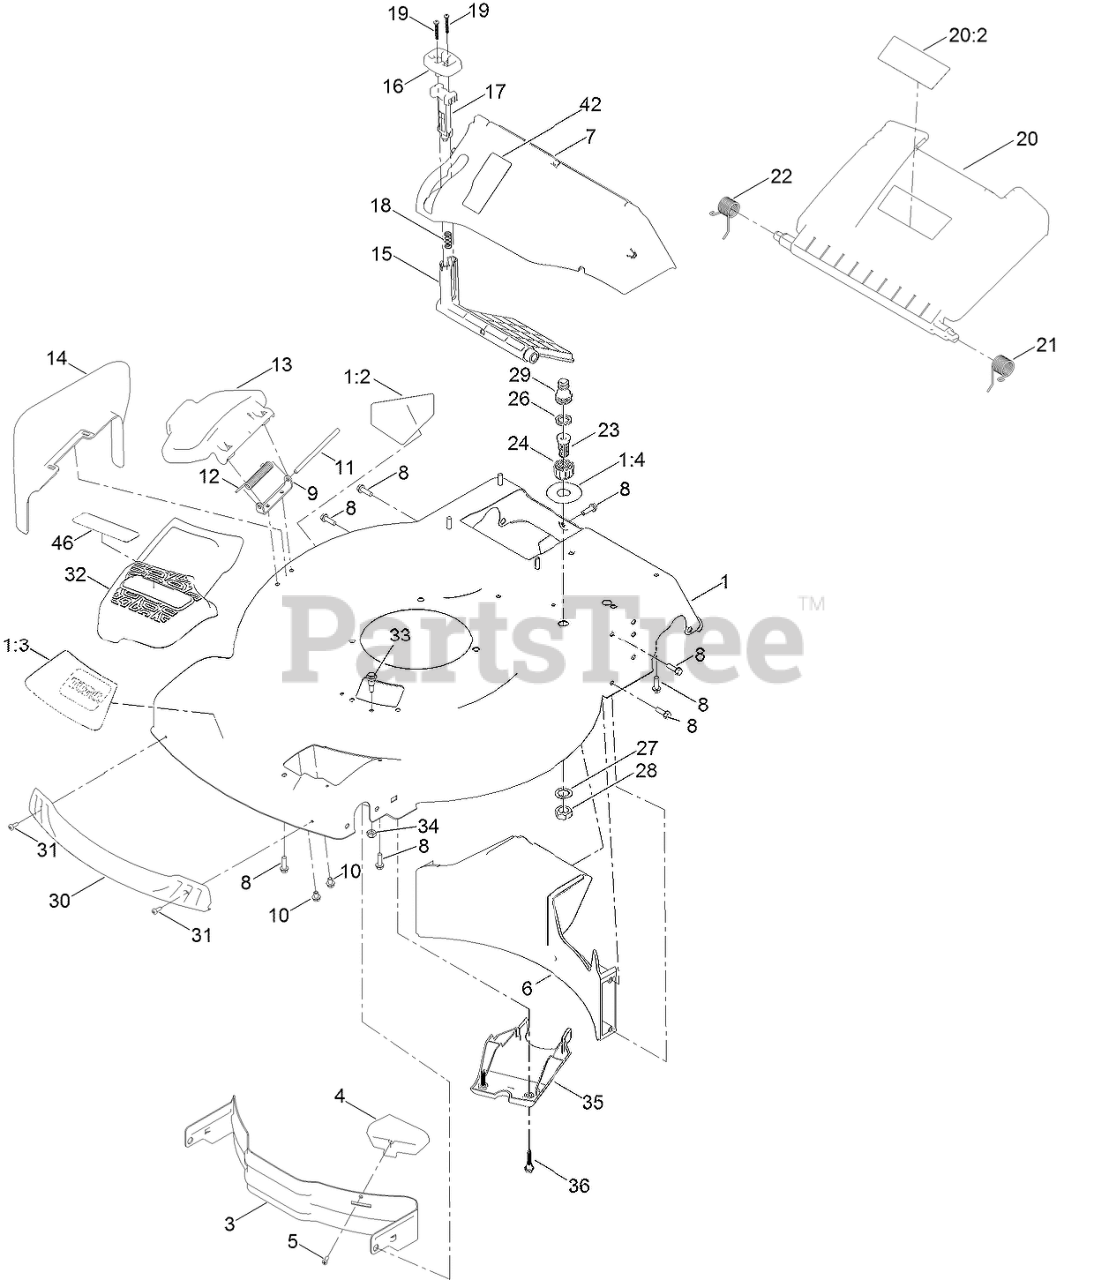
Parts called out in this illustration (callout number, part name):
1	HOUSING ASM
1:2	DECAL-DANGER
1:3	DECAL-DECK
1:4	DECAL-QUICK WASH
3	BAFFLE-FRONT
4	KICKER-FRONT
5	SCREW-PPH
6	BAFFLE-REAR
7	CHUTE-RECYCLE
8	SCREW-HWH
9	BRACKET-COVER
10	SCREW-HWH
11	ROD-COVER
12	SPRING-TORSION
13	DEFLECTOR-SIDE
14	CHUTE-DISCHARGE, SIDE
15	DEFLECTOR-RECYCLE
16	KNOB-RECYCLE
17	LATCH-RECYCLE
18	SPRING-COMPRESSION
19	SCREW-PPH
20	REAR DOOR ASM
20:2	DECAL-WARNING
21	SPRING-TORSION
22	SPRING-TORSION
23	PORT-WASHOUT
24	COUPLING-HOSE, WASHOUT PORT
26	WASHER-SEAL, WASHOUT PORT
27	WASHER-TOOTH, INTERNAL
28	NUT-JAM
29	ADAPTER-CONNECT, QUICK
30	BUMPER
31	SCREW-FORMING, THREAD
32	COVER-BELT, FRONT
33	BOLT-SHOULDER
34	NUT-LOCK, NI
35	COVER-BELT, FRONT
36	SCREW-SHOULDER, HHF
46	DECAL-BELT COVER, POWEREVERSE
